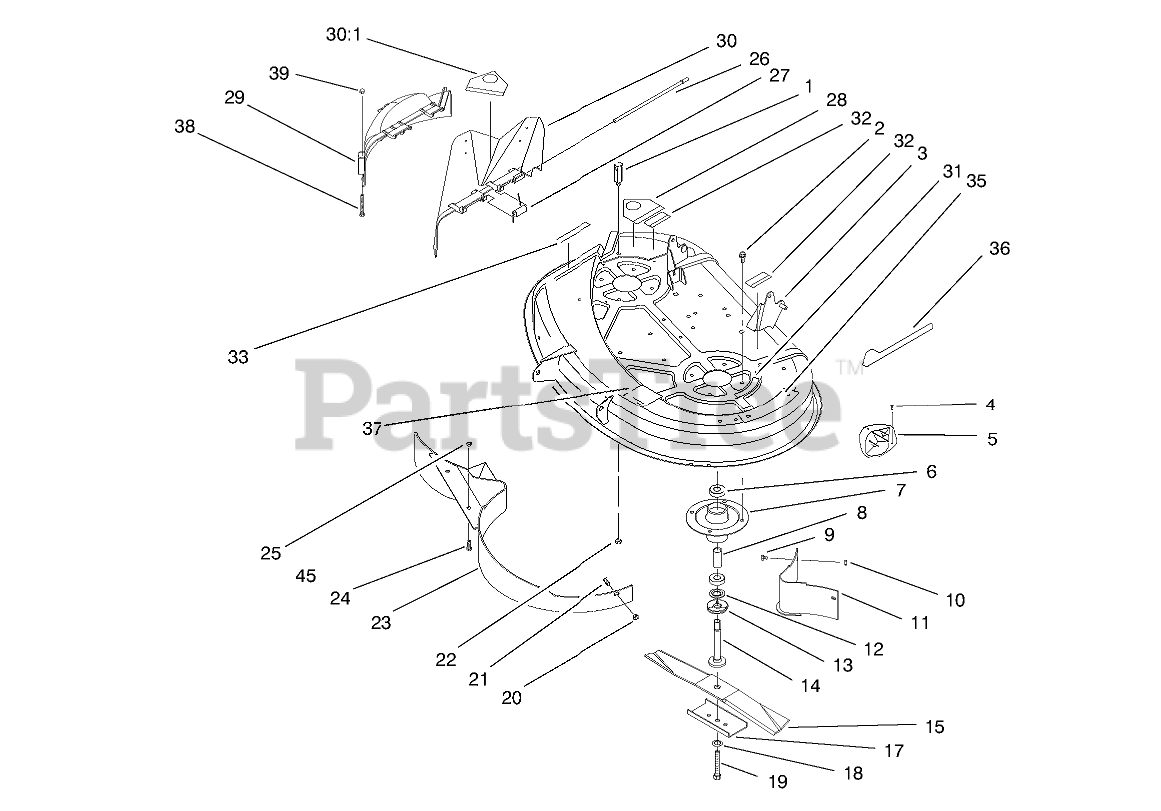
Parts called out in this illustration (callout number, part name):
1	REAR PIVOT POST (PLTD)
2	SCREW-TAPTITE
3	Deck Wa-38"
4	SCREW-PPH
5	PLATE-KICKER
6	BEARING-BALL
7	HOUSING-SPINDLE
8	SPACER
9	SCREW-HH
10	NUT-LOCK, NI
11	BAFFLE ASM
12	SPACER
13	SHIELD-BEARING
14	SHAFT-SPINDLE
15	Blade
17	STIFFENER-BLADE
18	WASHER-BELLEVILLE
19	SCREW-HH
20	NUT-LOCK, NI
21	BOLT-CARR
22	NUT-LOCK, NI
23	BAFFLE ASM
24	SCREW-HH
25	NUT-LOCK, NI
26	ROD-HINGE DEFLECTOR
27	SPRING
28	DECAL-DANGER
29	COVER-RECYCLER
30	DEFLECTOR ASM
30:1	DECAL-DANGER
31	DECAL-DANGER, SHIELD
32	DECAL-WARNING
33	DECAL-DANGER, DEFLECTOR
35	DECAL-DANGER
36	DECAL-RECYCLER DECK 38"
37	DECAL-ROUTING, BELT
38	SCREW-HH
39	NUT-CAP
